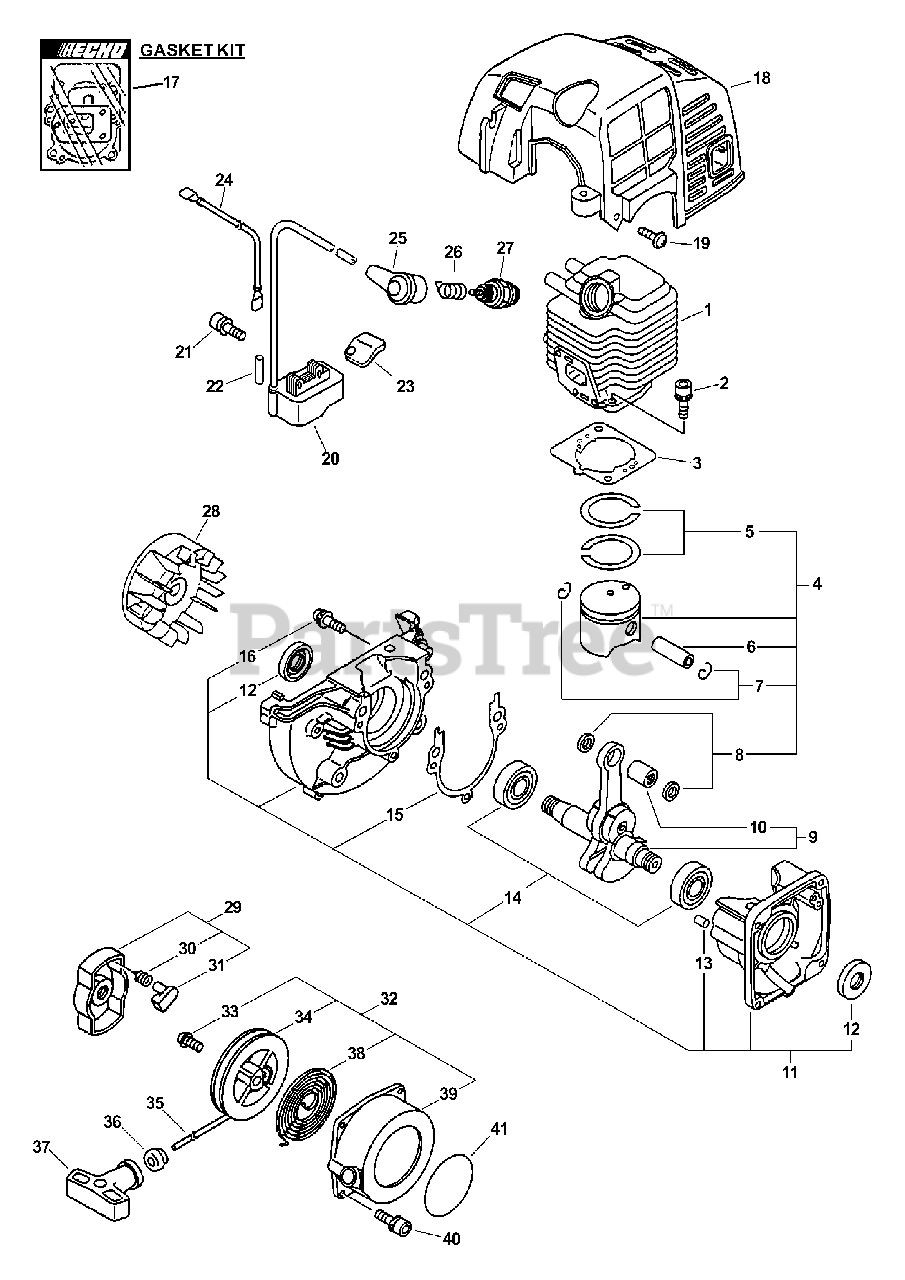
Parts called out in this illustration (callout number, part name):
1	CYLINDER
2	SCREW - 5X22
3	GASKET, CYLINDER
4	PISTON KIT
5	RING, PISTON
6	PIN, PISTON
7	RING, RETAINING
8	SPACER, PISTON
9	CRANKSHAFT ASSY
10	BEARING, NEEDLE - 8
11	CRANKCASE KIT
12	SEAL, OIL
13	PIN - LOCATING
14	BEARING, BALL - 6201
15	GASKET, CRANKCASE
16	SCREW - 5X28
17	GASKET KIT
18	COVER, ENGINE
19	SCREW - 4X14
20	COIL, IGNITION
21	SCREW - 4X20
22	TUBE, INSULATOR
23	COVER, DUST
24	LEAD - IGNITION
25	CAP, SPARK PLUG
26	TERMINAL, SPARK PLUG CAP
27	SPARK PLUG -- BPM-8Y
28	FLYWHEEL
29	STARTER PAWL ASSY
30	SPRING, RETURN
31	PAWL, STARTER - BLACK
32	STARTER ASSY
34	REEL, ROPE
35	ROPE, STARTER - 3X1000
36	GUIDE, ROPE
37	GRIP, STARTER
38	SPRING, REWIND
39	CASE, STARTER
40	SCREW - 4X16
41	LABEL - ECHO
